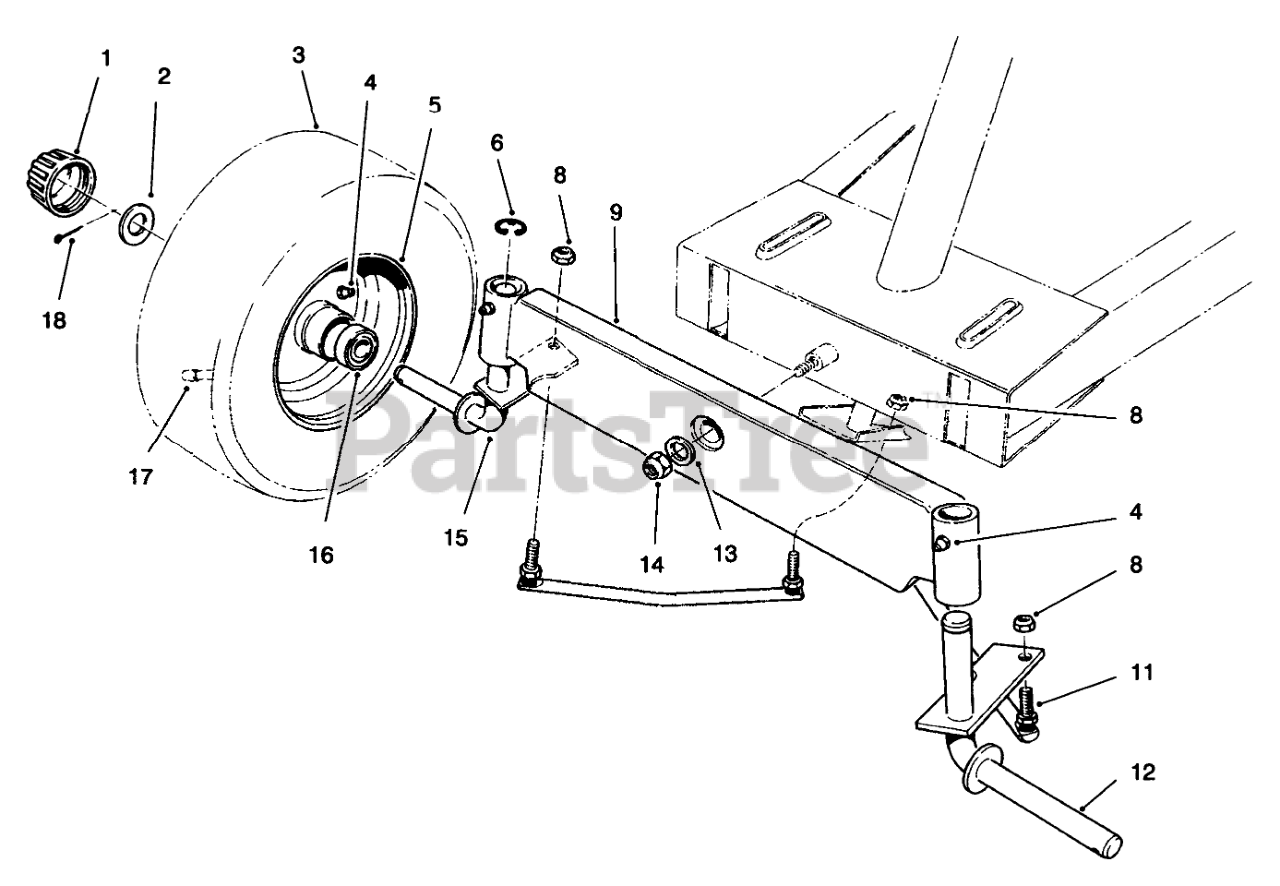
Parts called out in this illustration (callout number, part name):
1	CAP-HUB
2	WASHER-PLAIN
3	TIRE,PNEU.11X4.00X5
4	FITTING-GREASE
6	E-RING
8	NUT-LOCK
9	Axle-Front
11	TIE ROD ASM
12	WHEEL SPDLE WA LH (RED)
13	WASHER-FLAT
14	NUT-LOCK, NI
15	WHEEL SPDLE WA RH (RED)
16	BEARING-WHEEL
17	STEM-VALVE
18	PIN-COTTER
